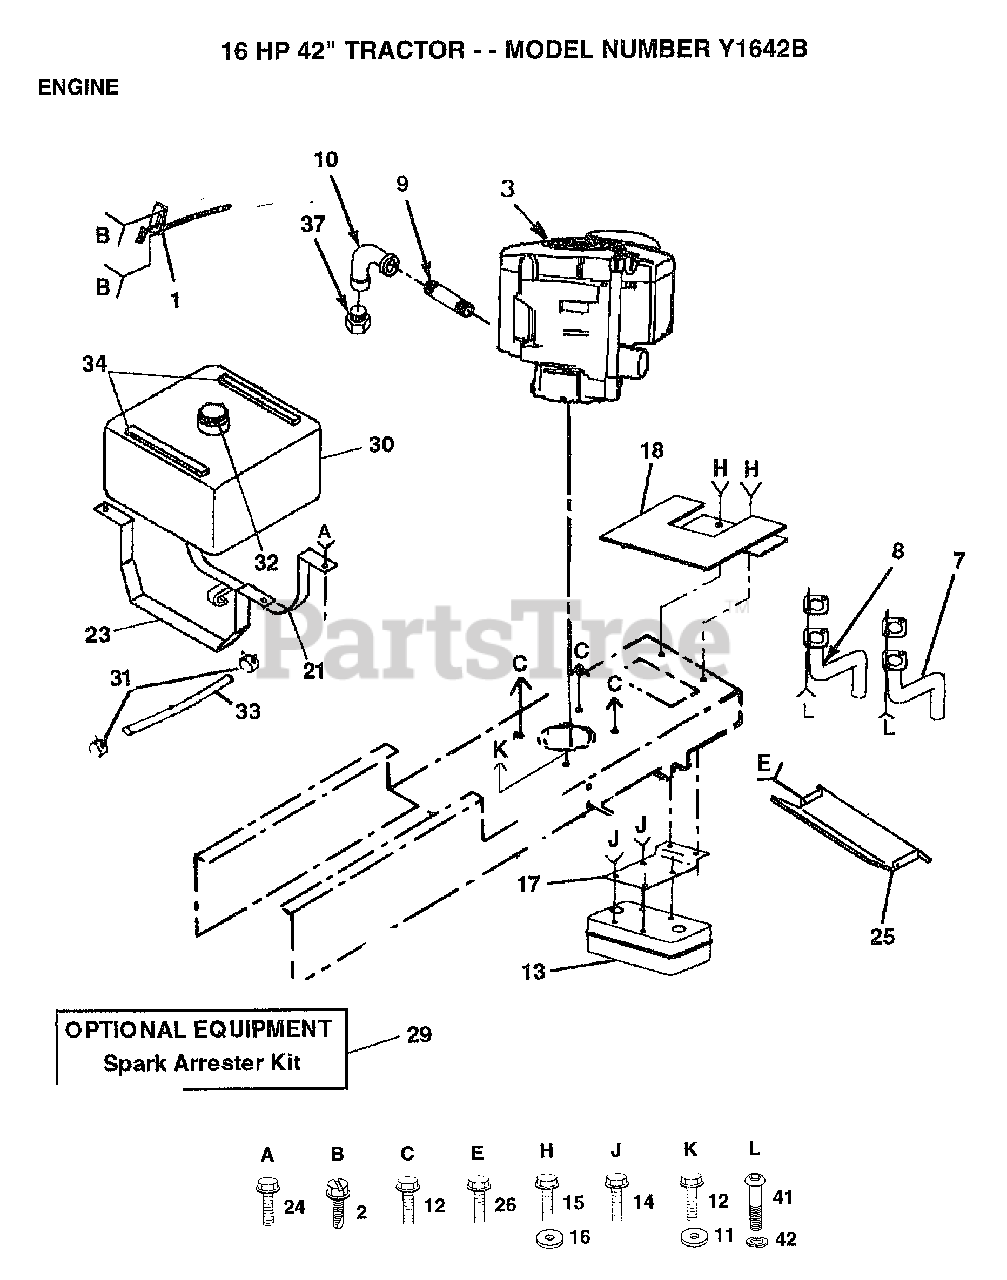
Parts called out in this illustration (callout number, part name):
1	CONTROL.THROTTL
2	SCREW LT
7	"TUBE,MANIFOLD RH"
8	"TUBE,MANIFOLD LH"
9	PIPE NIPPLE LT
10	ELBOW
11	LOCKWASHER
12	SCREW LT
14	SCREW ST
15	SCREW
16	WASHER
17	BRACKET MUFFLER
21	STRAP ASM. F.TANK
23	"STRAP,TANK"
24	SCREW LT
25	HEAT SHIELD
26	SCREW
29	SPARK ARREST KIT
31	HOSE CLAMP
34	"STRIP,FORM"
41	SCREW
42	LOCKWASHER
